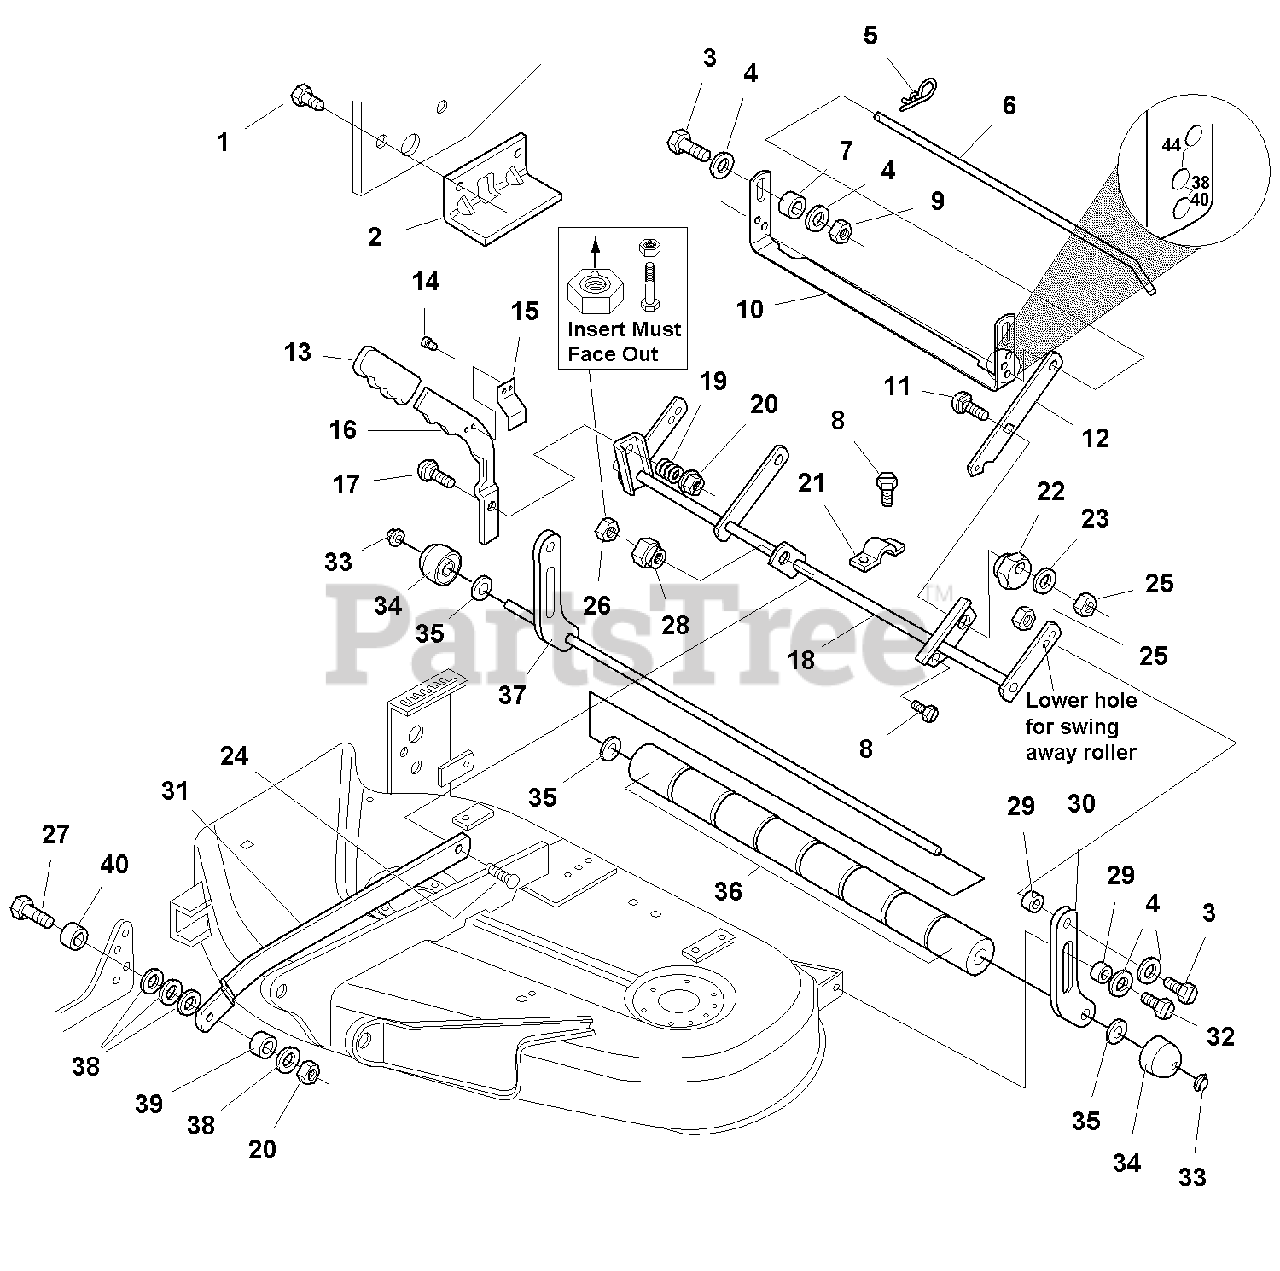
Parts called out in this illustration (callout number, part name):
1	CAPSCREW, Taptite Hex Washer Head, 5/16-18 x 3/4
2	BRACKET, Upstop
3	CAPSCREW, Hex Head, 5/16-18 x 1-1/4
4	WASHER, 5/16
5	CLIP, Spring
6	ROD, Transport
8	CAPSCREW, Hex Head Taptite, 5/16-18 x 3/4
9	NUT, Hex Lock, 5/16-18
10	U-BRACKET
11	CARRIAGE BOLT, 5/16-18 x 1-1/4
15	SPRING, Handle
16	ADJUSTMENT ARM
17	CARRIAGE BOLT, 3/8-16 x 1-3/4
18	ROCKER ARM ASSEMBLY, (Use lower hole with swing away rollers.)
20	NUT, Hex Flange Lock, 3/8-16
21	STRAP
23	WASHER, Flat, 5/16
24	CARRIAGE BOLT, 3/8-16 x 1-1/2
25	NUT, Hex, Flangelock, 5/16-18
26	NUT, Hex Lock Aluminum Insert, 3/8-16
27	CAPSCREW, Hex Head, 3/8-16 x 2
28	NUT, Hex Adjusting, .99 DIA .687
30	BAR, Roller, Support
32	CAPSCREW, Taptite Hex Washer Head, 5/16-18 x 1
33	PUSHNUT, 5/8
34	ROLLER, End
35	WASHER, 5/8
37	SHAFT ASSEMBLY
38	WASHER, Flat, 3/8
